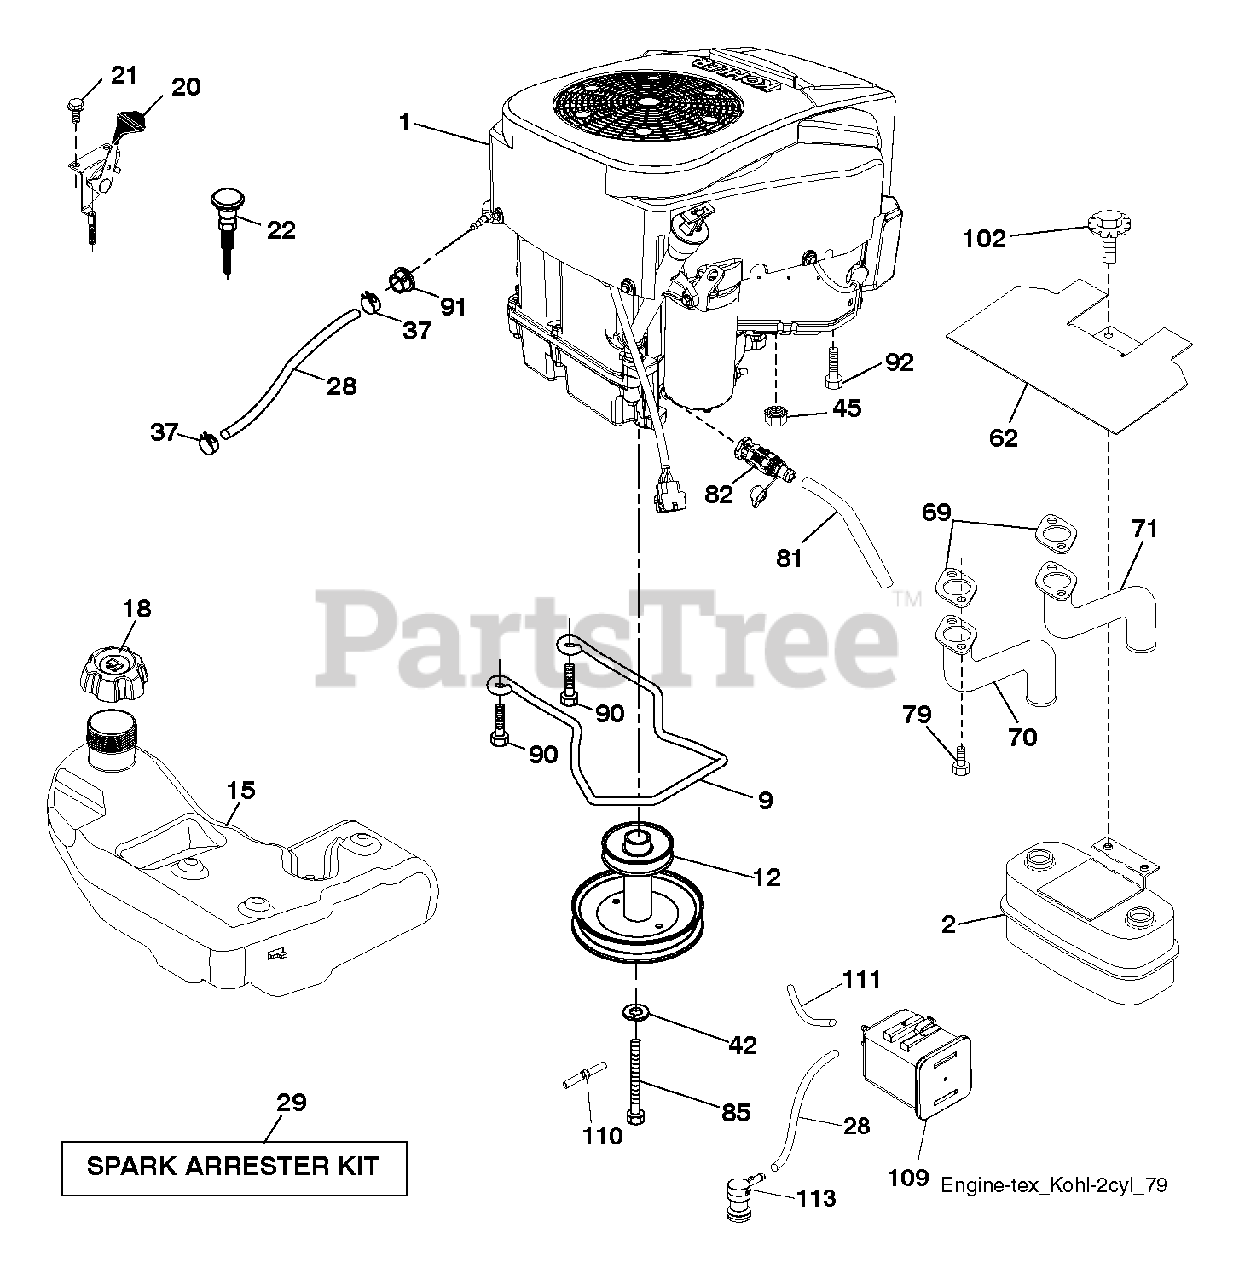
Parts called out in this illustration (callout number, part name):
2	Muffler Assembly, Twin MN
9	KEEPER.BELT.ENG.4.25"2.BLT.431
12	ENGINE.PULLEY
15	Fuel Assembly Tank, 3 Gallon
18	CAP ASSY FUEL 3" GRAY
20	THROTTLE CONTROL
21	SCREW.#10 X 0.750.BOS
22	CONTROL.CHOKE.ERGO.PUSH-IN.BLA
28	LINE.FUEL.64"REAR.EMIS
29	KIT.SPARK ARRESTOR 794945 B&S
37	HOSE CLAMP
42	WASHER 7/16 LOCK
45	NUT
62	SHIELD.HEAT.MUFFLER
69	GASKET.EXHAUST.KOHL.CV18-CV26
70	PIPE.EXHAUST.RH.CV18/20
71	PIPE.EXHAUST.LH.CV18/20
79	SCREW.SOCKET HD.5/16-1
81	TUBE, DRAIN OIL ASM.
82	VALUE.OIL.DRAIN
85	BOLT.HEX.7/16-20X4.GR5.1.5BLUE
90	SCREW 3/8-16X1
91	BUSHING.1.375OD
92	SCREW 3/8-16X1
102	SCREW
109	CANNISTER, CARBON
110	VALVE.ASM.ANTI-SLOSH
111	RP PURGE LINE
113	VALVE.SLANT.CARTRDG.90 DEG.TEX
